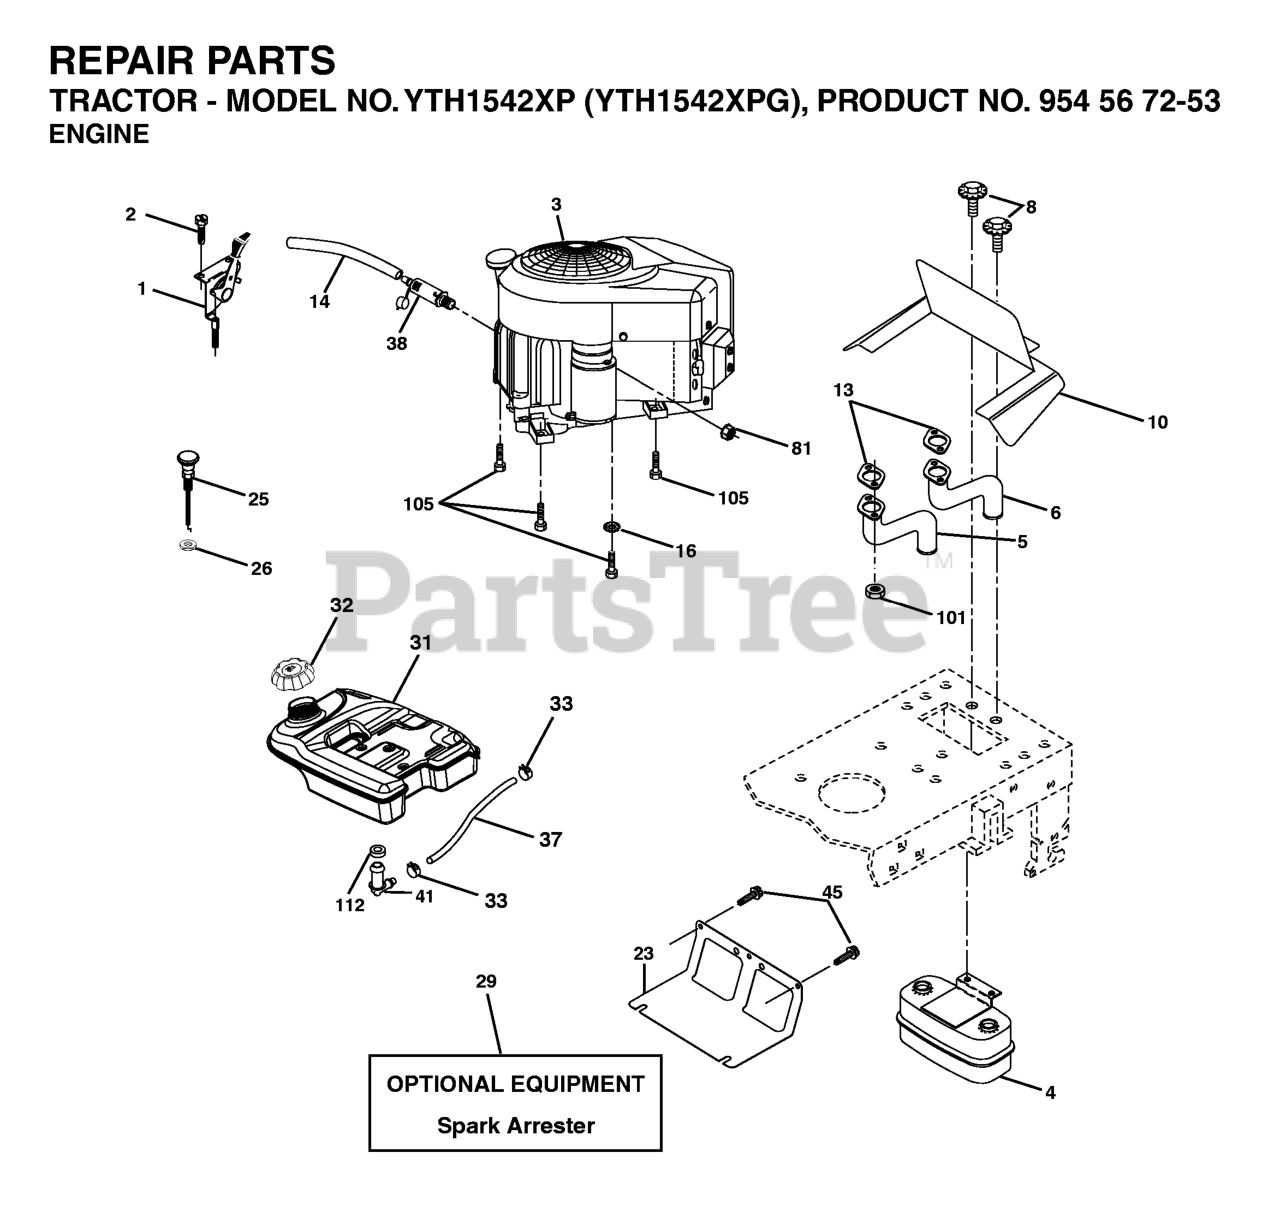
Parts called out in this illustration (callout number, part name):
1	CONTROL, THROTTLE
2	SCREW
4	MUFFLER.TWIN.CYL.LOW.TONE
5	EXHAUST TUBE LH KAWI
6	EXHAUST TUBE RH KAWI
8	BOLT.5/16-18UNCX3/4 W/SEMS.BLK
10	RP SHIELD HEAT MUFFLER
16	LOCKWASHER
23	SHIELD.BROWNING.DBR.GUARD
25	CHOKE CONTROL
26	Nut Keps 3/8 - 24 UNF
29	KIT.SPARK ARRESTOR 794945 B&S
31	4.0 REAR FUEL TANK
32	TANK CAP
33	HOSE CLAMP
37	REPL BY 532 00 85-43
41	STEM FUEL TANK
45	SCREW, 3/8-16X3/4
81	NUT
101	FLANGE NUT
105	SCREW 3/8-16X1
112	BUSHING OUTLET T
